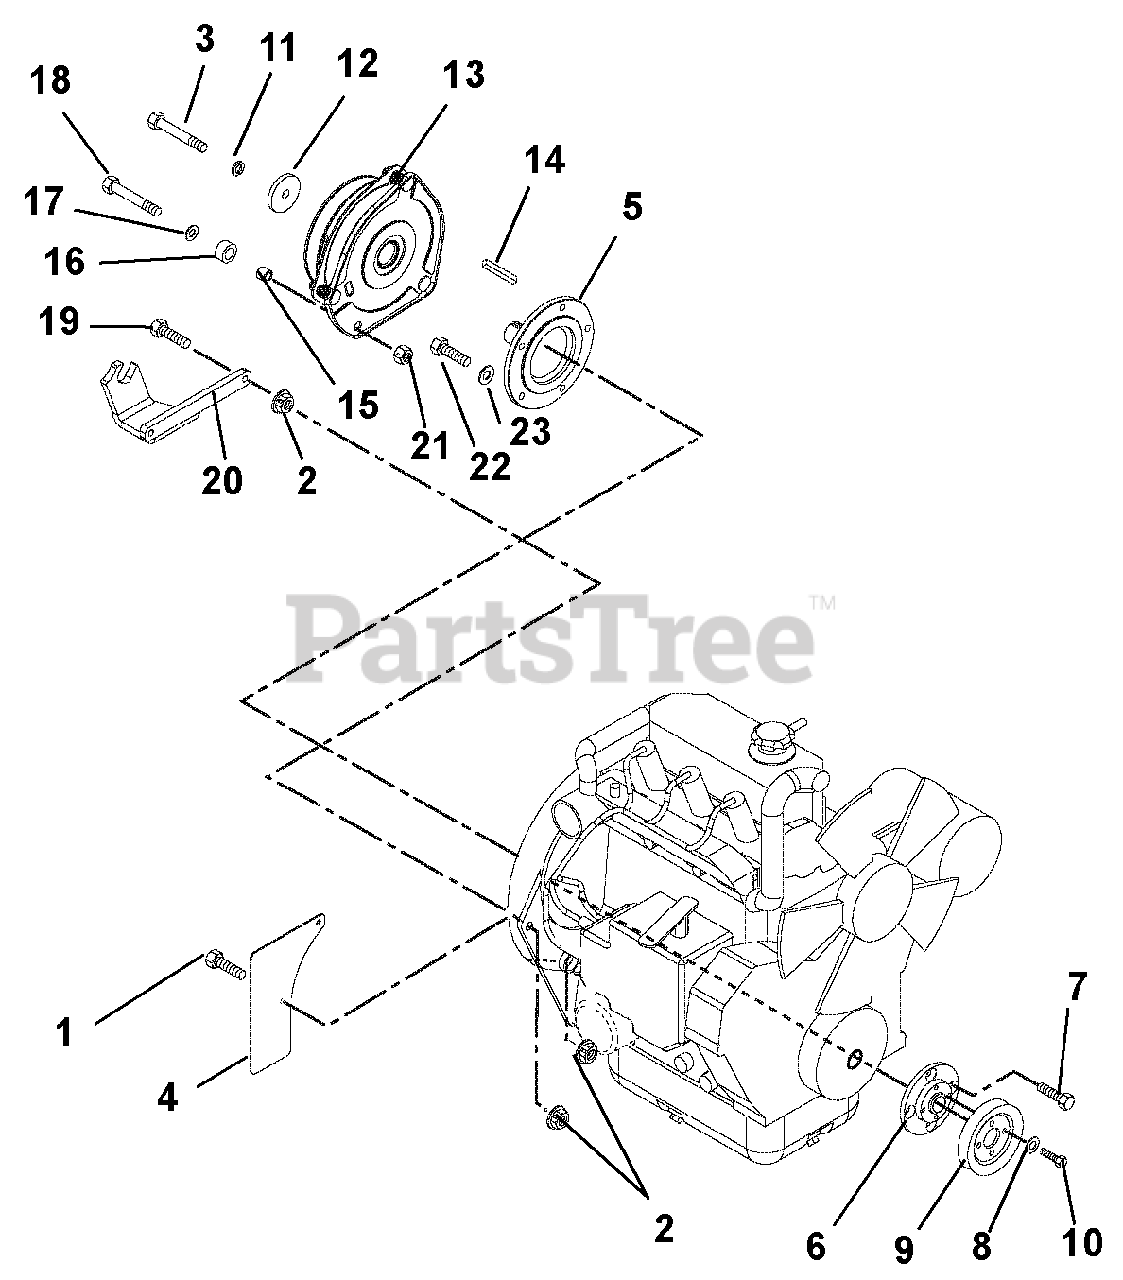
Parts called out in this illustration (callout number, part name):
1	Bolt, Hex .31-18 x .75 Grade 5
2	Nut, Locking Top Flange .31-18
3	Bolt, Hex .44-20 x 2.50 Grade 5 YZ EP80
4	Guard, Flywheel
5	Stub Shaft
6	Adapter, Sheave
7	Bolt, M8 1.25 x 25
8	Washer, Locking .25 x .062
9	Sheave, Poly V 1.0 x 3.25
10	Bolt, Hex .25-20 x .75 Grade 5
11	Washer, Locking .44 x .109 Regular
12	Washer, Flat Steel .469 x 2.00 x .25
13	Clutch, Ogura
14	Key .25 x .25 x 2.25
15	Spacer .375 x .688 x .500
16	Bumper, Rubber .62 x 1.0 x .51
17	Washer, Flat Steel .406 x .812 x .065
18	Bolt, Hex .38-16 x 1.00 Grade 5
19	Bolt, Hex .31-18 x 1.25 Grade 5
20	Bracket, Clutch Stop
21	Nut, Lock .375-16
22	Bolt, Hex M8 x 1.25 x .75 Gade 8
23	Washer, Lock .31 x .078 Reg
